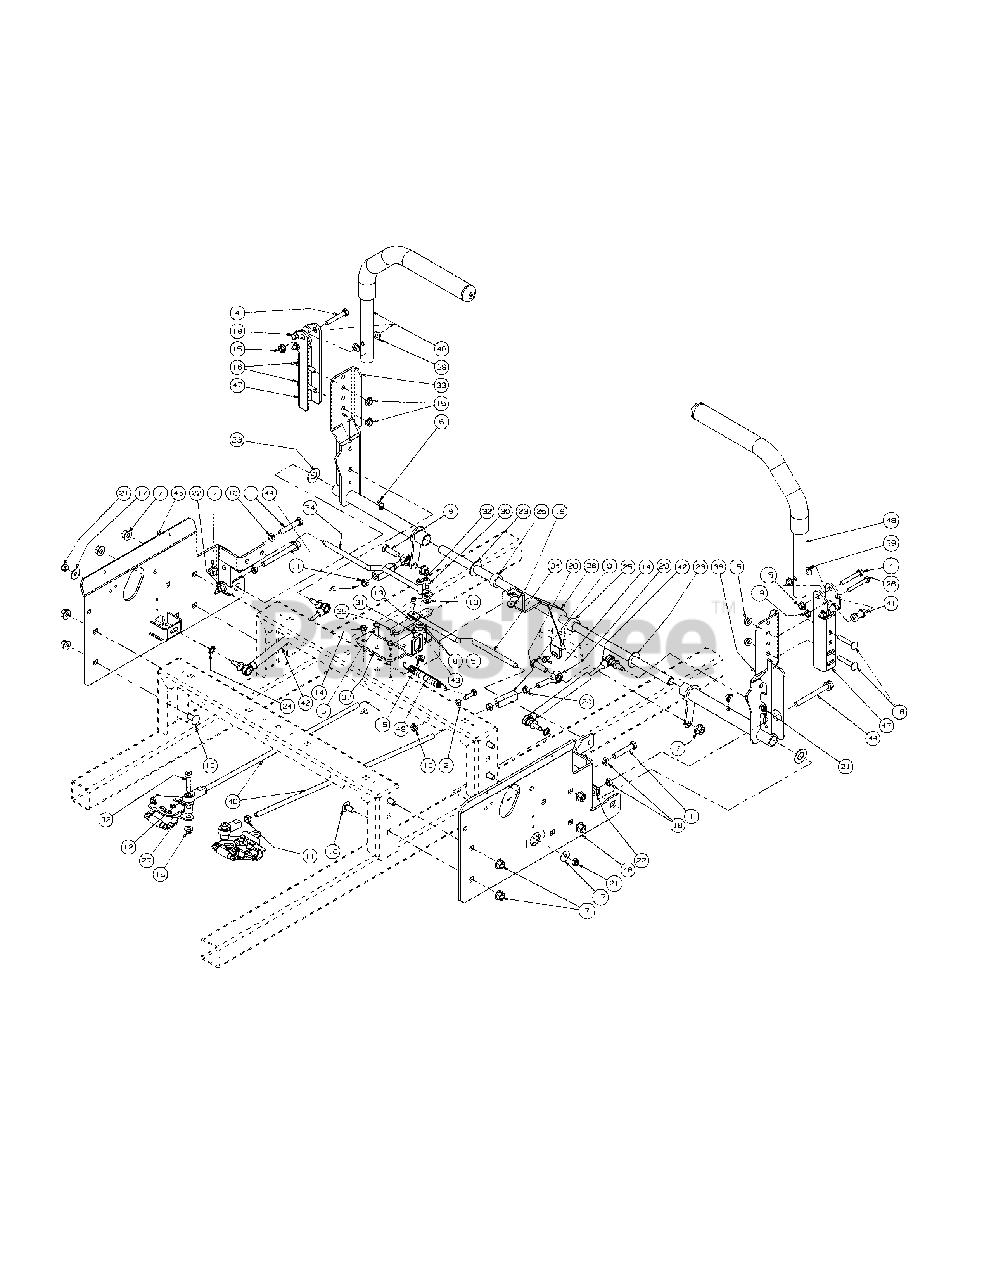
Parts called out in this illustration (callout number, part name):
1	Hex Cap Screw 3/8-16 x 2.00
2	Hex Nut, 1/4-20
3	Screw, Hex, Cap, 1/4-20 x .75
4	Hex Cap Screw, 5/16-18 x 2.00
5	HHCS, 1/4-20 x 1.00
6	Grease Fitting, 1/4-28, 45 degree
7	Hex Nut, 3/8-16, Lock Flange
8	Washer, 3/8, SS
9	Hex Cap Screw, 3/8-16 x 1.25
10	Carriage Bolt, 3/8-16 x .75
11	Hex Jam Nut, 3/8-24
12	B/Joint, 3/8-24, Right Hand Female
13	Flat Washer, 1.4 x .630 x .0515
14	Screw, TT, 1/4-20, 0.5, Hex Index Washer
15	Nut, Lock, HexFlange, 5/16-18
16	Carriage Bolt, 5/16-18 x 1.75
17	Belle Washer, .325 x .930 x .045
18	Nut, 3/8-16, Jam
19	Hex Flange Lock Nut, 1/4-20
20	Nut, 3/8-24, Jam, LH Third
21	Nut, Hex, Center Lock, M8
22	U-Nut, 3/8-16, .75
23	Flat Washer, 5/8 Nylon
24	External Washer, 3/8
25	Shaft Collar
26	HHCS, 1/4-20 x 2.0
27	Spacer, .625 OD x .385 ID x 1/2
28	Turnbuckle
29	B/Joint, 3/8-24, Left Hand Female
30	Shoulder Bolt, 1/4 x 1/4
31	Nut w/ Star Washer, 10-24
32	Screw, Shoulder Control Rod
34	Brake/Control Rod
35	Lapbar Control Arm
36	Lapbar Control Shaft Assembly
37	Lapbar/Brake Control Mounting Bracket
39	Bushing, .310 x .172 x .688 x .06
40	Control Rod, 3/8-24 x 19.50
41	Spacer, .25 ID x .38 OD x 1.13
42	Cylinder Return to Neutral
43	Spacer, .405 ID x 1.0 OD x .72
44	Hex Cap Screw, 3/8-16 x 3.50
45	Side Panel, Control, Left
46	Side Panel, Control, Right
47	Lapbar Pivot Bracket
48	Lapbar Assembly includes:
49	Extension Spring, .53 OD x 4.75
